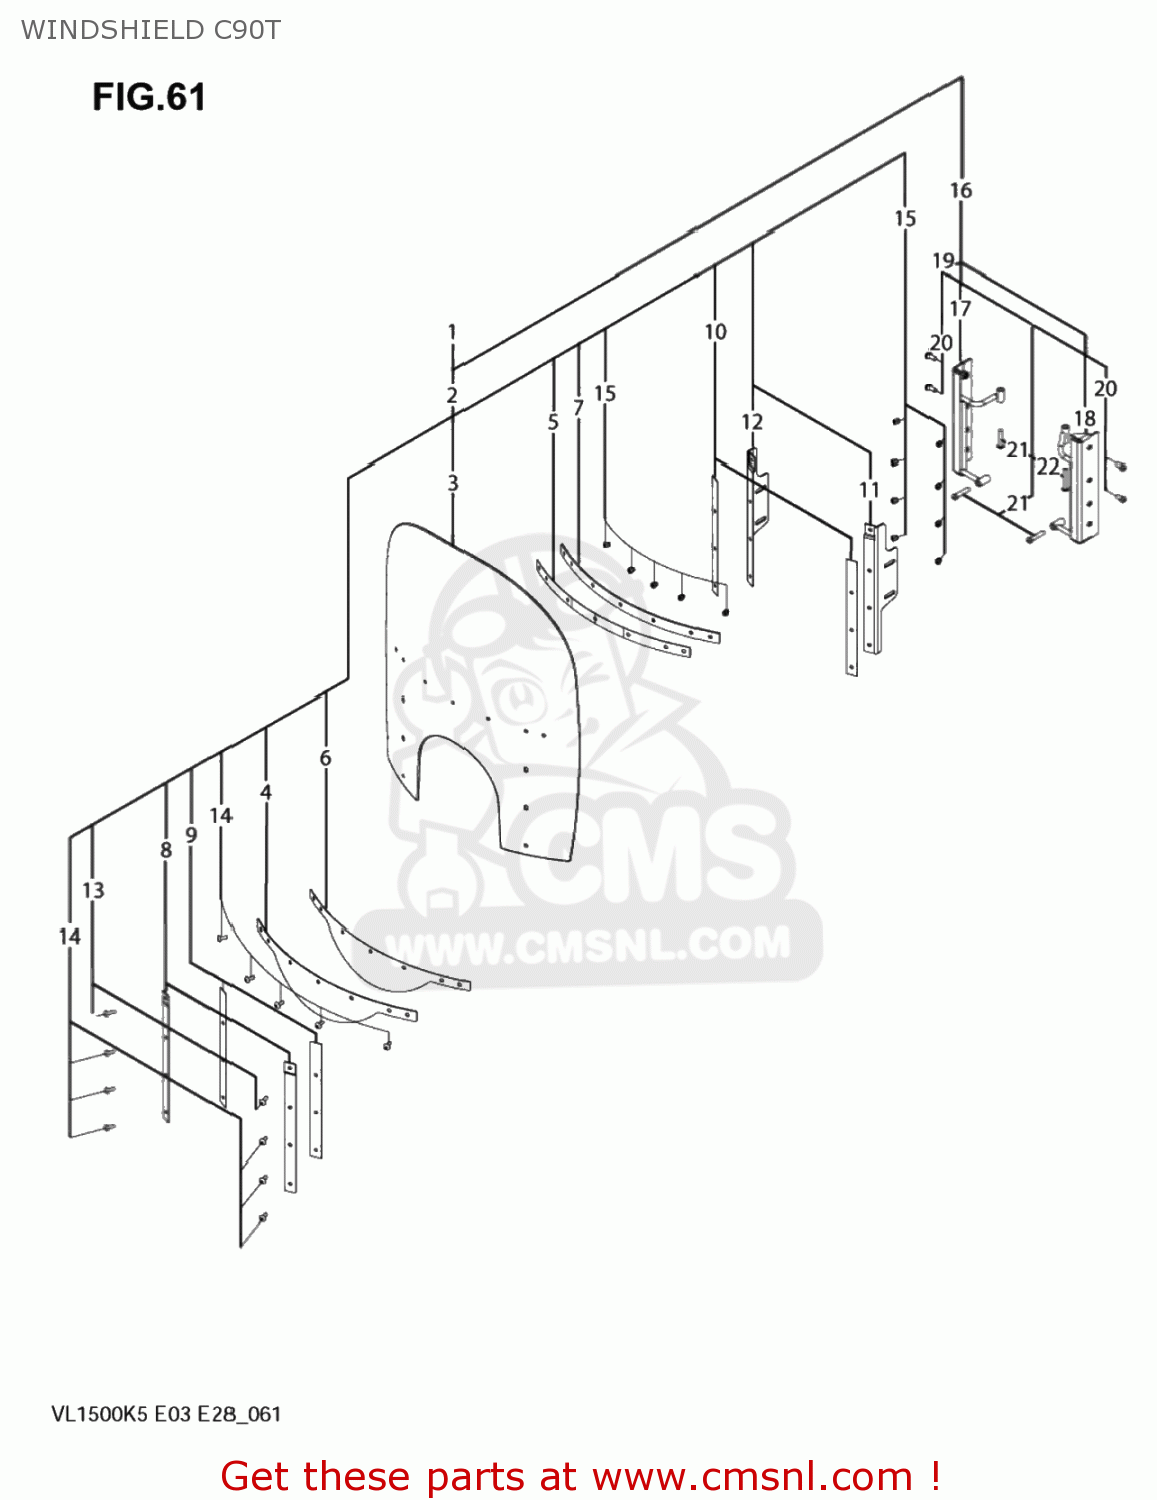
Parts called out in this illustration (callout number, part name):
1	C90T CLASSIC WN
3	VL15C90 WNDSHLD
4	OUTSIDE PLATE,HORIZONTAL
5	GASKET,HORIZONTAL (NAS)
6	GASKET,HORIZONTAL (NAS)
7	INSIDE STRIP,HORIZONTAL
8	OUTSIDE STRIP,VERTICAL
9	GASKET,VERTICAL,STRIP (NAS)
10	GASKET,VERT,INSIDE STRIP (NAS)
11	BRACKET,FRAME,VERTICAL,LH
12	BRACKET,FRAME,VERICAL,RH
13	CAP SCREW M6-1.0X20,SS,
14	CAP SCREW M6-1.0X16,SS,
15	NUT,HEX CAP, M6-1.0 88
16	MOUNTING KIT
17	STAY,WINDSHIELD,RH
18	STAY,WINDSHIELD,LH
20	CAP SCREW M8-1.25X16,SS
21	BOLT,M8-1.25X40,SS
22	BOLT,M8-1.25X50,SS
23	EMBLEM,BOULEVARD
24	LOWER ASSEMBLY,LH
25	LOWER ASSEMBLY,RH
26	TURN SIGNAL BAR
